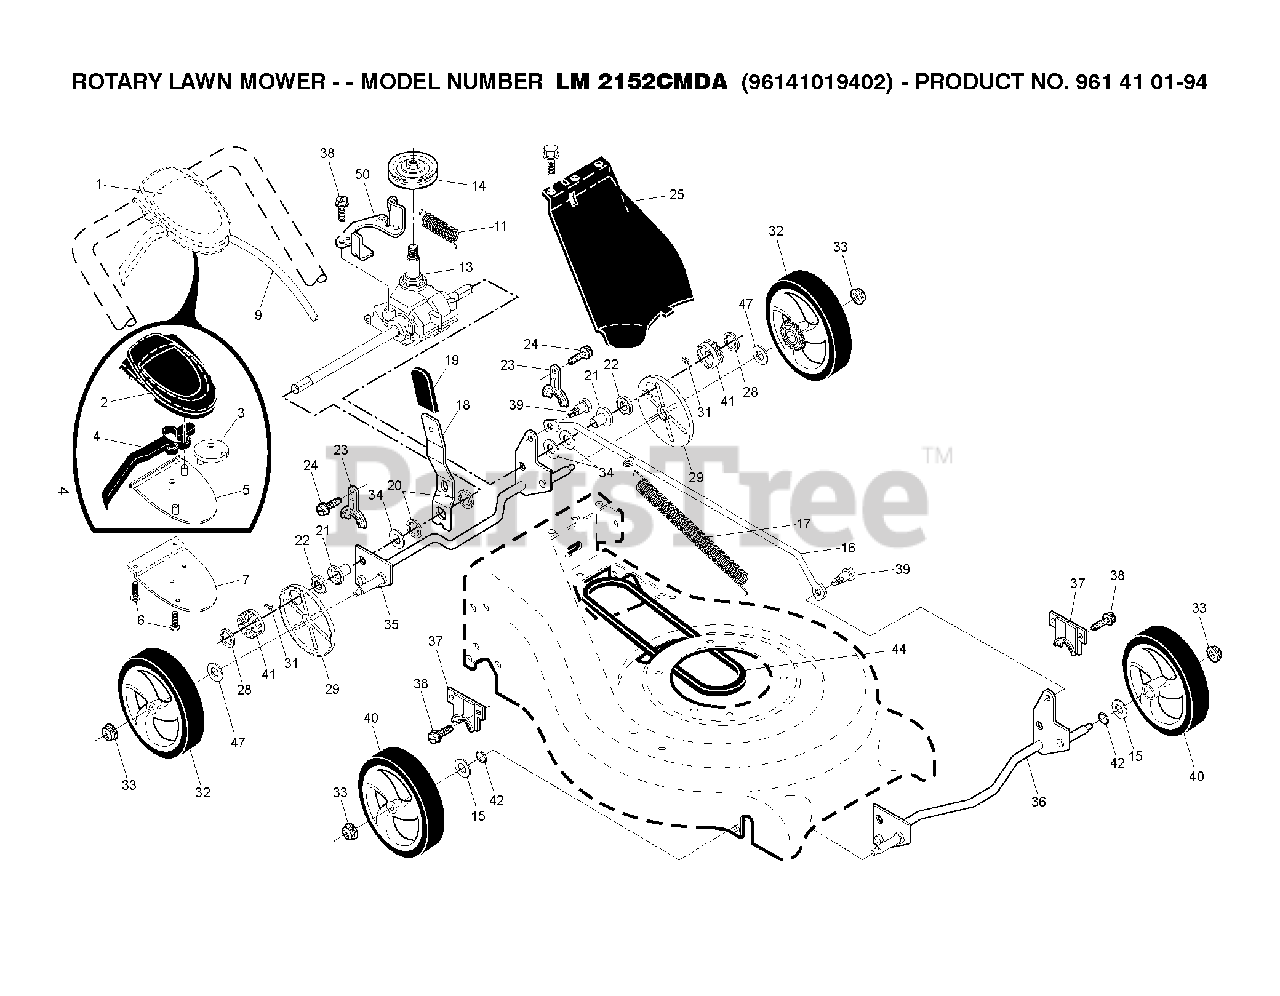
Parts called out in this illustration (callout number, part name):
2	COVER, TOP DRIVE CONTROL
3	PULLEY.CAM.DRIVE.CONTROL.EZ
5	COVER BOTTOM DRIVE CNTRL BLACK
6	SCREW, PHILLIPS HEAD 10 X 5/8
7	BRACKET.DRIVE.CONTROL.MOUNT
9	CABLE.ASSY.RGD.EZ.AUTO
13	TRANSMISSION.21.RWGD
14	PULLEY.1.PIECE
15	WASHER PM
16	ROD.CONNECTING.SPT.BLACK
17	SPRING EXTENSION
18	SPRING.SELECTOR.
19	KNOB, SELECTOR SPRING
21	BEARING SUPPORT
22	BEARING
23	BRACKET
24	SCREW 14-20 X 5/8
28	E-RING 7/16 RE
29	COVER.DUST.WHEEL
31	PAWL, DRIVE
33	NUT.HEX.FLANGE.3/8-16.LOCKNUT
35	SHAFT ASSY REAR
36	SHAFT ASSY, FRONT
37	RETAINER.FRONT.SHAFT
39	SHOULDER BOLT SEMI GIMLET PT.
41	PINIION.14.TOOTH.RGD
42	O-RING..070X.487.NEOPRENE
44	BELT.RGD.VS
47	WASHER FLUT
50	BELT KEEPER
